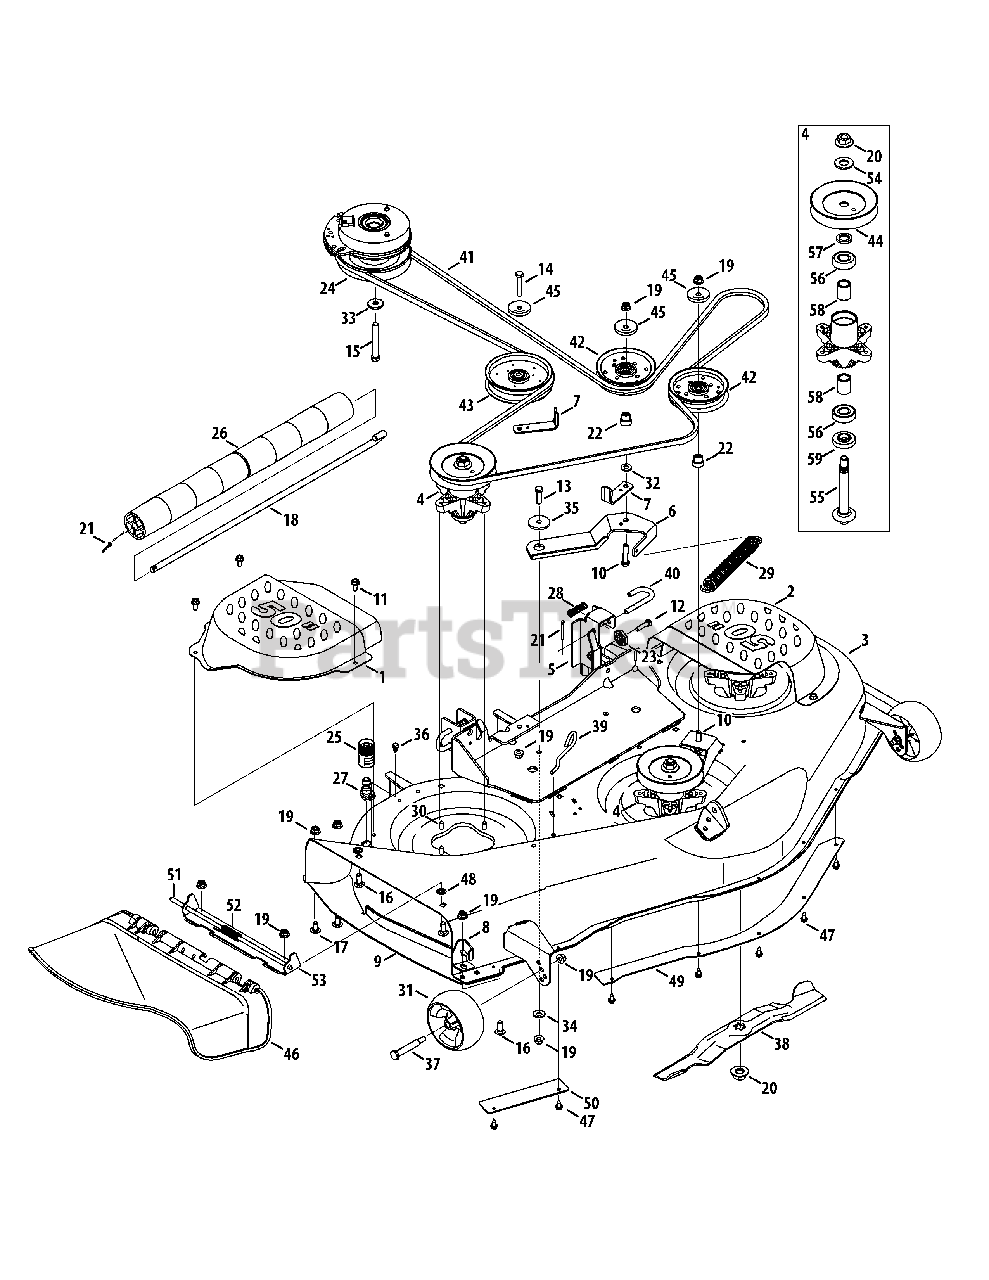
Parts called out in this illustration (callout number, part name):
1	Belt Cover, RH
2	Belt Cover, LH
3	50-Inch Deck (w/o front roller)
4	Spindle Assembly
5	Deck Lift Bracket
6	Idler Arm
7	Bracket Belt Guard
9	Finger Guard
10	Hex Cap Screw 3/8-16 x 1.75
11	Hex Washer Screw 5/16-18 x .750
12	Hex Cap Screw 5/16-18 x 1.25
13	Hex Cap Screw 3/8-16 x 1.25
14	Hex Cap Screw 3/8-16 x 2.00
15	Screw 7/16-20 x 3.25
16	Carriage Screw 3/8-16 x 1.00
17	Carriage Screw 3/8-16 x .75
18	J-Hook
19	Flange Lock Nut 3/8-16
20	Hex Flange Nut 5/8-18
21	Cotter Pin 5.32 x 1.25
22	Shoulder Spacer
23	Deck Adjustment Gear
24	Electric PTO Clutch
25	Water Nozzle Adapter
26	Front Roller
27	Deck Wash Nozzle
28	Compression Spring .66 x 1.9
29	Extension Spring 1.25 OD x 1.751
30	Hex Washer Head Screw 5/16-18 x .75
31	Deck Ball Wheel 5.0
32	Flat Washer .385 x .870 x .092
33	Flat Washer .450 x 1.25 x .164
34	Bell Washer .45 x 1.0 x .062
35	Shoulder Spacer .884 x .190
36	Shoulder Screw .500 x 1/4-20
37	Shoulder Screw .5 x 2.5 x 3/8-16
38	Blade 2 in 1, 17.9
39	Deck Spring Rod
40	Deck Hanger Rod
41	V-Belt
42	Idler Pulley 4.25 Dia
43	Idler Pulley 5.00 Dia.
44	V-Type Pulley 5.39
45	Pulley Cap
46	Discharge Chute Assembly
47	Hex Washer Screw 1/4-20 x .625
48	Push Nut 3/8
49	Center Skirt
51	Hinge Pin
52	Torsion Spring
53	Chute Bracket
54	Flat Washer .76 x 1.50 x .12
55	Spindle Shaft, 5.75
56	Ball Bearing
57	Spacer .79 x 1.25 x .175
58	Spacer .80 x 1.10 x 1.32
59	Spacer .79 x 1.82 x .55
